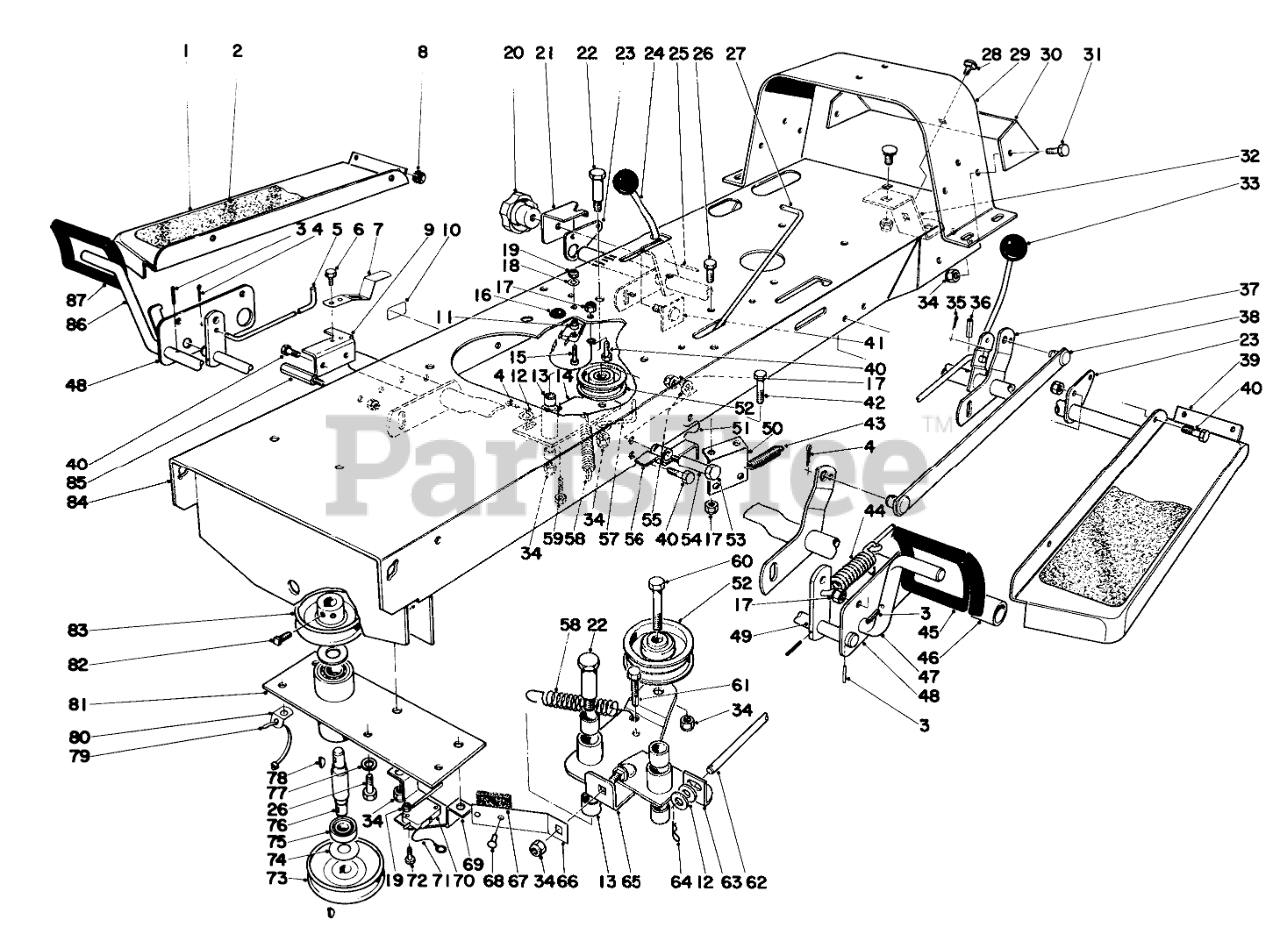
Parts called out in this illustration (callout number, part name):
1	Footrest
2	Foot Pad
3	PIN-SPRING
4	PIN-COTTER
5	Clutch Rod
7	Brake Lock
8	NUT-KEPS
9	Bracket-Brake Lock
10	Decal Brake
11	Spacer
12	WASHER-FLAT
13	BUSHING
14	Idler Arm (Incl. Ref. #13)
15	SCREW-PPH
16	GROMMET
17	NUT-LOCK, CONE
18	WASHER
19	NUT-LOCK, NI
21	Slide Height Adj.
22	Axle Bolt
23	Bracket Tube
24	Rod Control Hgt. Adj.
25	PIN-ROLL
26	SCREW-HH
27	Brake Rod
28	SCREW-CARR
29	Rear Support
30	Frame Member Rear
31	SCREW-HH
32	Bracket Hitch
33	KNOB-CONTROL
34	NUT-LOCK, CONE
35	PIN-COTTER
36	1/8 X 1-3/8 ROLL PIN
37	Rear Height Adj. Tube
38	Height Adj. Link
39	Footrest
40	SCREW-HH
41	Knob Plate
42	SCREW-HH
43	Spring
44	Spring Brake Rod
45	CLUTCH PAD
46	Front Height Adj. Tube
47	Clutch Pedal
48	Plate Tube
49	Arm Lever
50	Belt Guide
51	Retainer Clutch Lock
52	PULLEY-IDLER
53	SCREW-HH
54	Spacer
55	WASHER-PLAIN
56	Clutch Lock
57	Belt Retainer
58	Spring
59	Sems Screw
60	SCREW-HH
61	Sems Screw
62	Clutch Rod Blade
63	Pivot Bracket
64	PIN-COTTER
65	Idler Plate (Incl. Ref. #13)
66	Clutch Brake
67	BLADE BRAKE LINING
68	Rivet
69	Bracket Switch
70	MICRO SWITCH
71	Wire Assembly
72	SCREW-HEAD, PAN
73	Pulley
74	Bearing Washer
75	Bearing
76	Pulley Shaft
77	WASHER-LOCK
78	KEY-WOODRUFF
79	Cable Tie
80	Strap Cable Tie
81	Pulley Tube
82	5/16-18 X 1/2 SQ HD
83	Pulley
84	Frame
85	Pedal Stop
86	Brake Pedal
87	PAD-BRAKE
